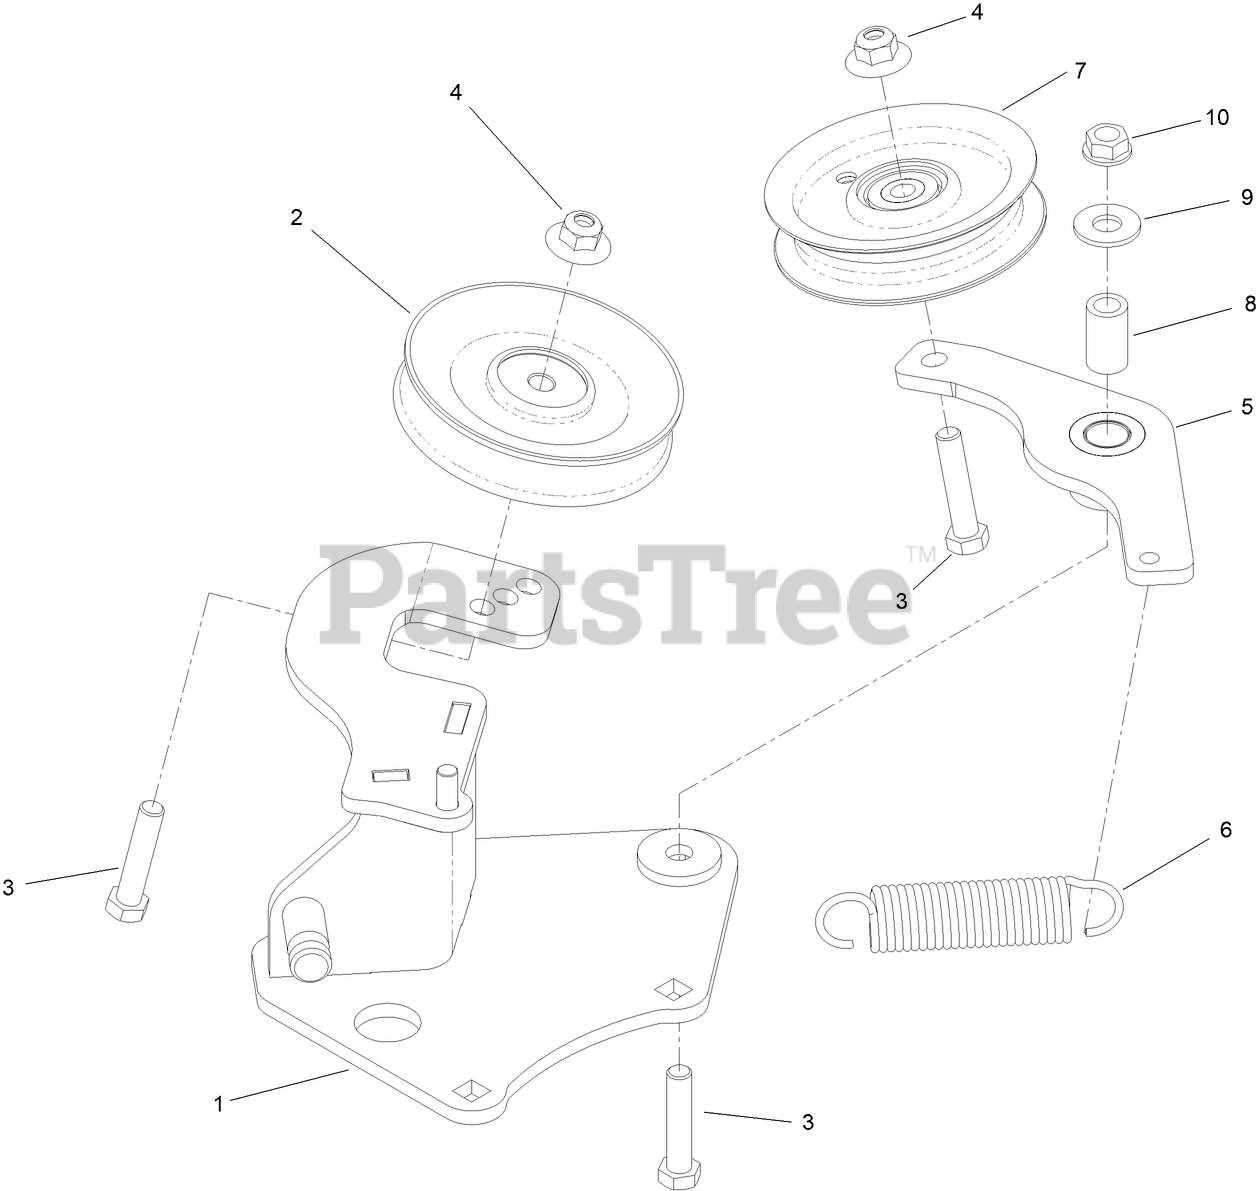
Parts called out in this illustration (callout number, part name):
1	BRACKET-IDLER
2	PULLEY-IDLER
3	SCREW-HH
4	NUT-FLANGE, NI
5	IDLER ASM
6	SPRING-EXTENSION
7	PULLEY-IDLER, FLAT
8	BUSHING-PIVOT, IDLER
9	WASHER-FLAT
10	NUT-HHF, WHIZ
